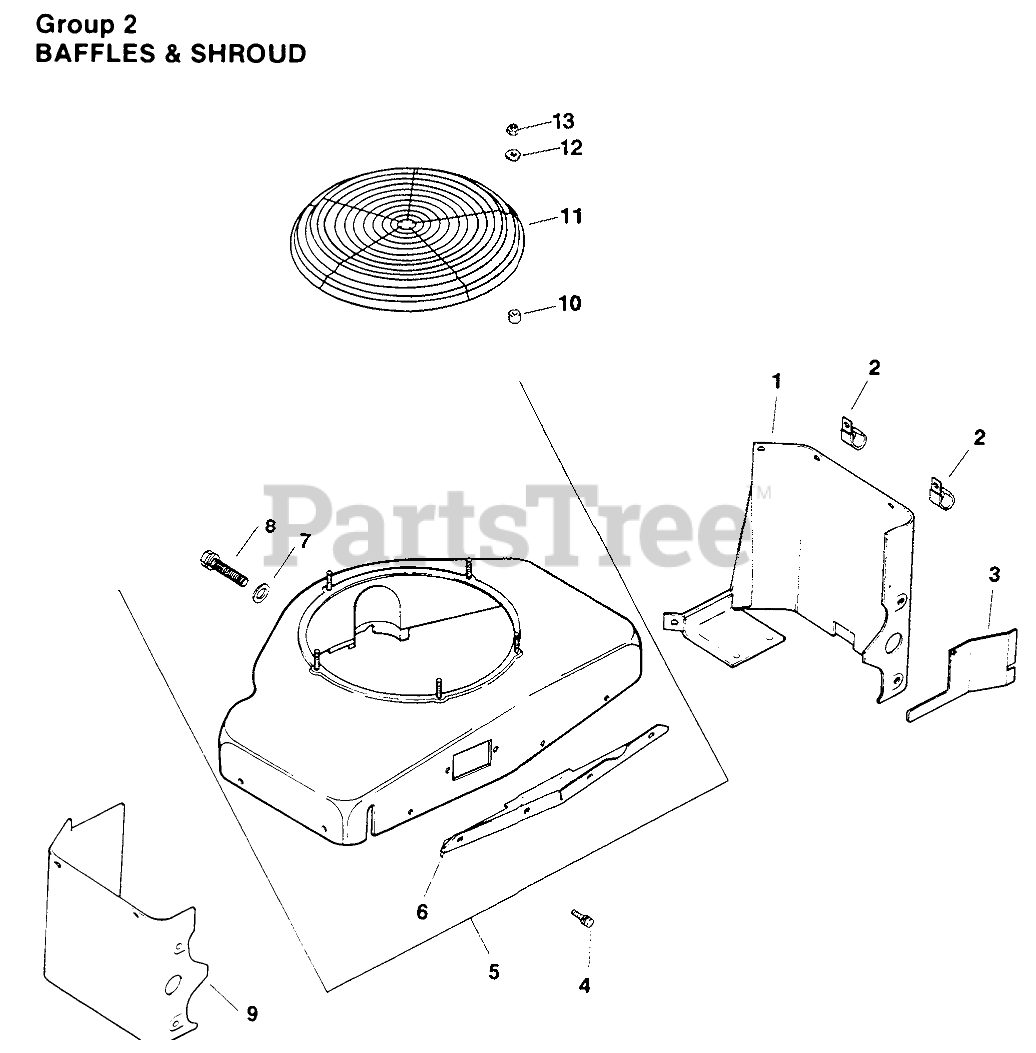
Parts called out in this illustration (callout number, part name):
1	Baffle-Cylinder Head
2	Clamp
3	Baffle-Cylinder Head
4	Screw
5	Kit-Blower Housing (Incl. Ref. #6-8)
6	Support-Upper Housing
7	Washer
8	Screw-Self Tap
9	Baffle-Cylinder Head
10	Spacer
11	Guard-Grass Screen
12	Washer
13	Locknut
